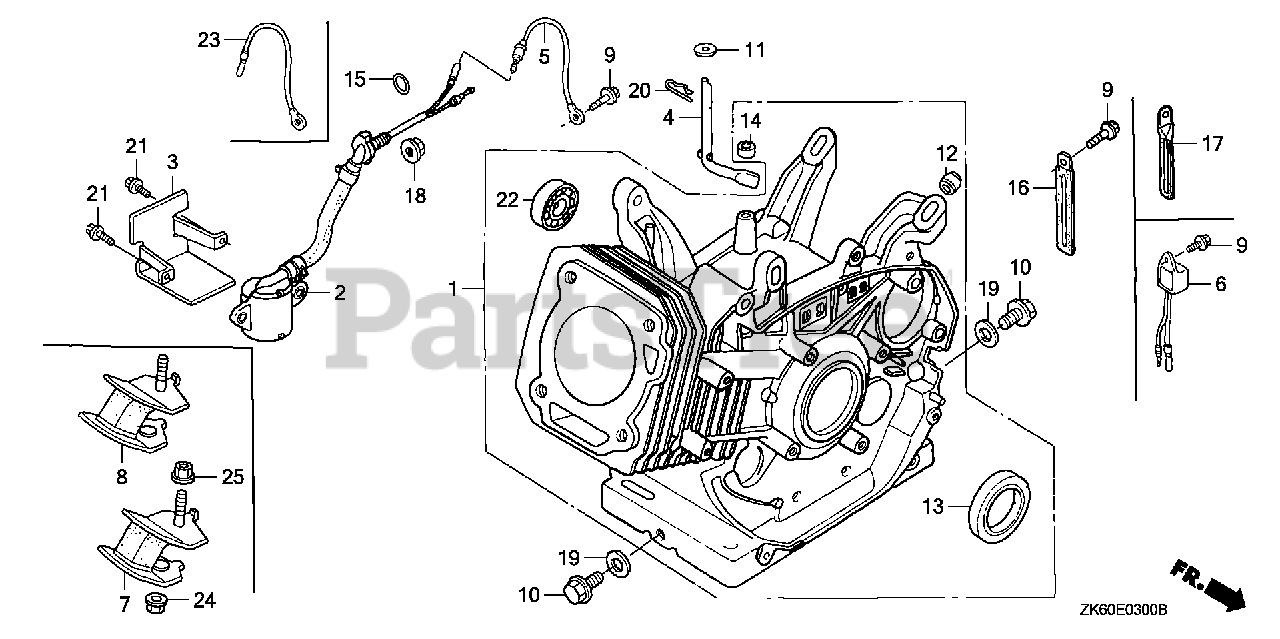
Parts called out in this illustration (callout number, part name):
1	CYLINDER ASSY. (SELF STARTER+ALERT)
2	SWITCH ASSY., OIL LEVEL
4	SHAFT, GOVERNOR ARM
10	BOLT, DRAIN PLUG (12X15)
11	WASHER (8.2X17X0.8)
13	OIL SEAL (35X52X8)
14	OIL SEAL (8X14X5)
15	O-RING (13.5X1.5) (ARAI)
15	O-RING (14MM) (NOK)
18	NUT, FLANGE (10MM)
19	WASHER, DRAIN PLUG (12MM)
20	PIN, LOCK (10MM)
21	BOLT, FLANGE (6X12)
22	BEARING, RADIAL BALL (6202)
